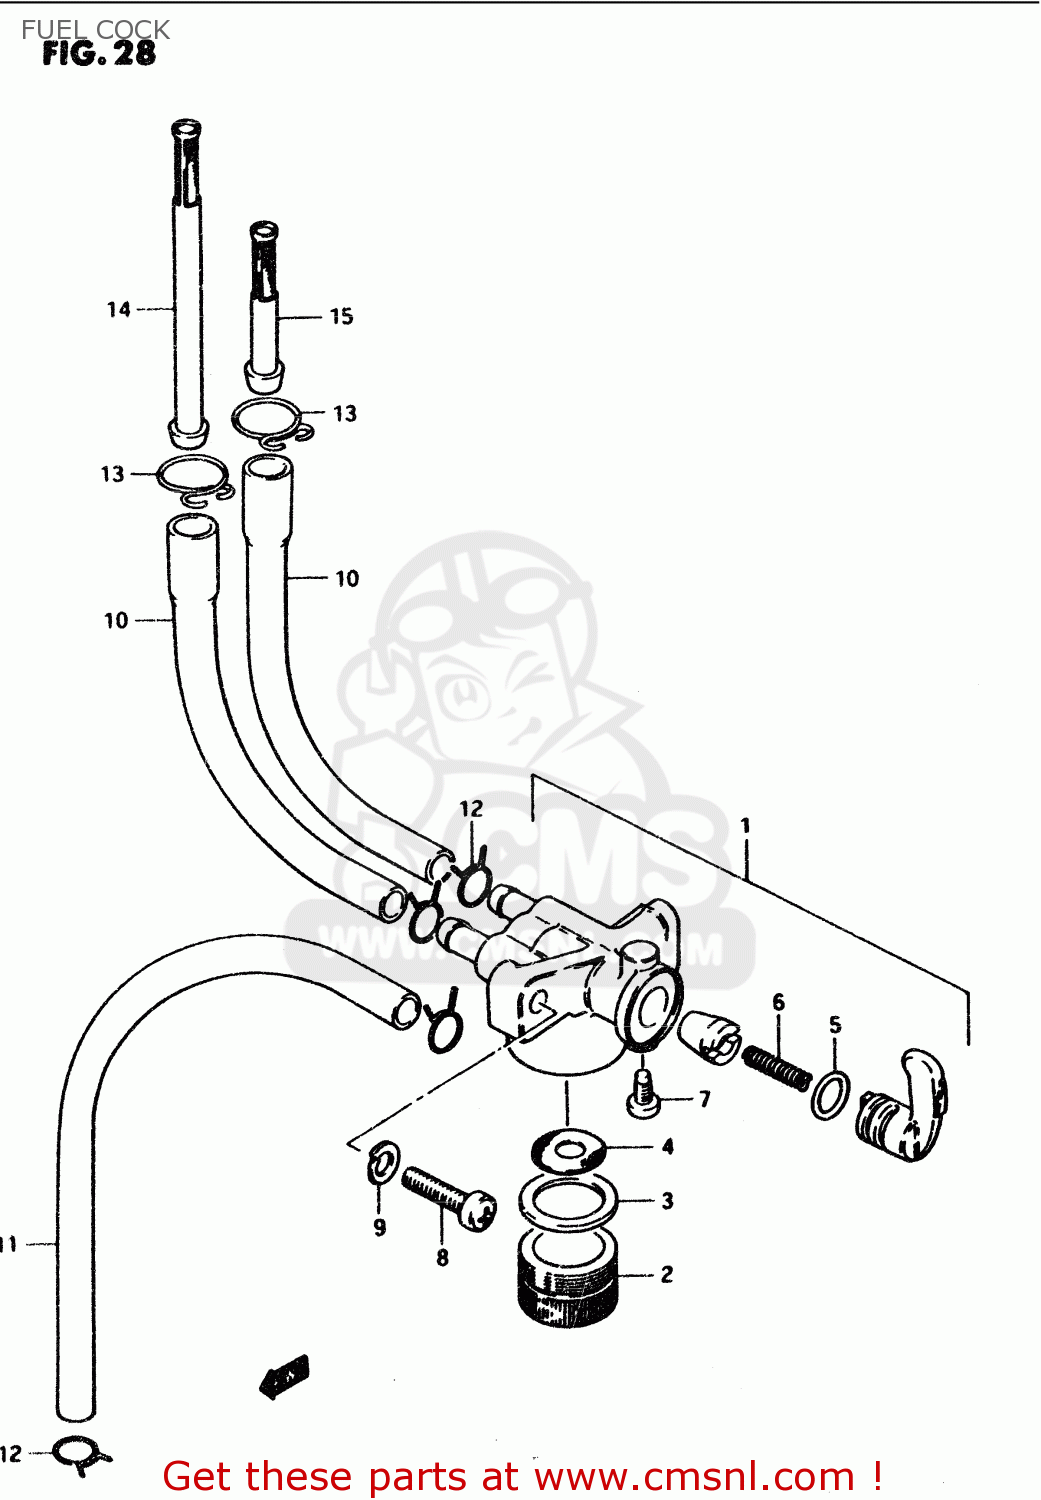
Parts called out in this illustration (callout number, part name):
1	COCK ASSY,FUEL
2	CUP
3	GASKET,FUEL FILTER CUP (NAS)
4	NET,FILTER
5	O RING,LEVER
6	SPRING
7	SCREW
8	SCREW
9	LOCK WASHER
10	HOSE,FUEL
11	HOSE
12	CLIP
13	CLIP
14	FILTER,FUEL
15	FILTER,FUEL
